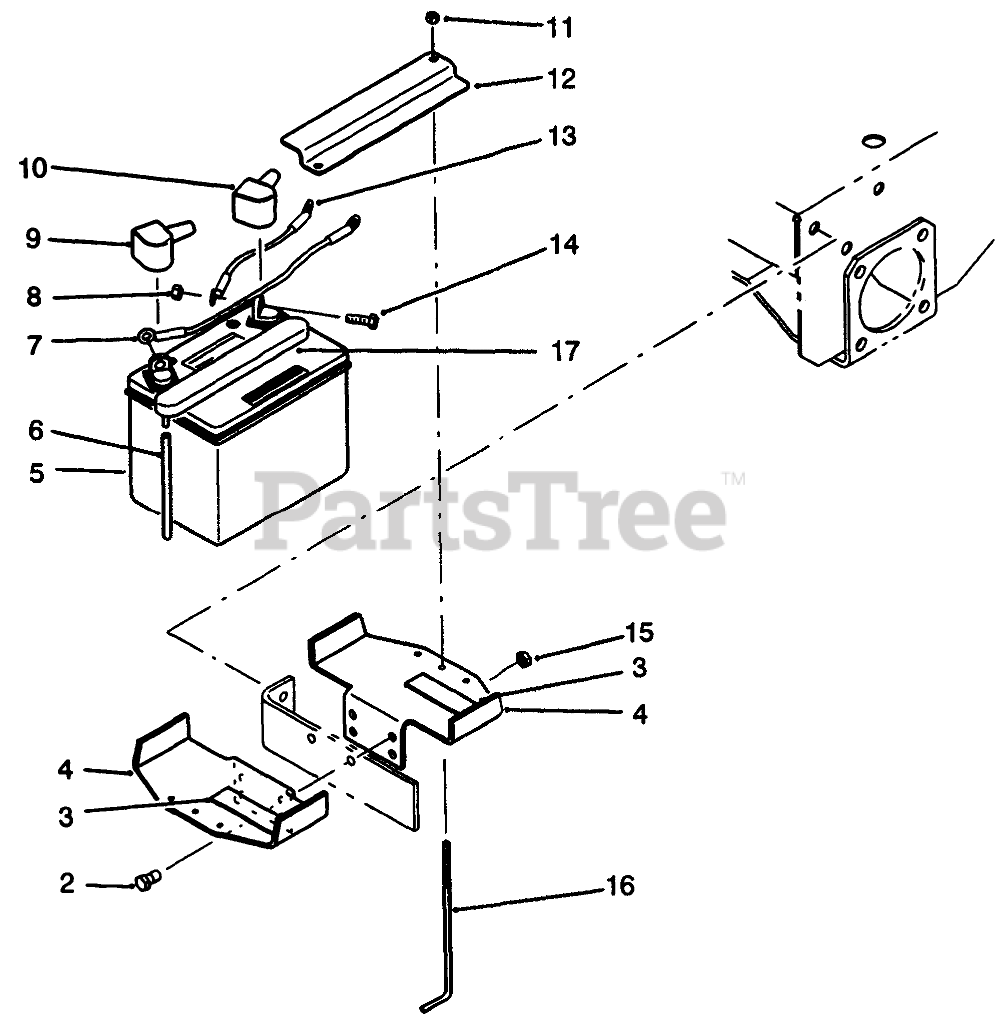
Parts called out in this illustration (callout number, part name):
2	SCREW-HH
3	PAD-TANK, FUEL
4	Battery
5	Battery
6	TUBE-VENT
7	WIRE ASM
8	NUT-KEPS
9	BOOT-TERMINAL, BLACK
10	BOOT-TERMINAL, RED
11	NUT-LOCK, NI
12	Clamp-Battery
13	WIRE ASM
14	SCREW-HH
15	NUT-LOCK, NI
16	ROD-SUPPORT, BATTERY
